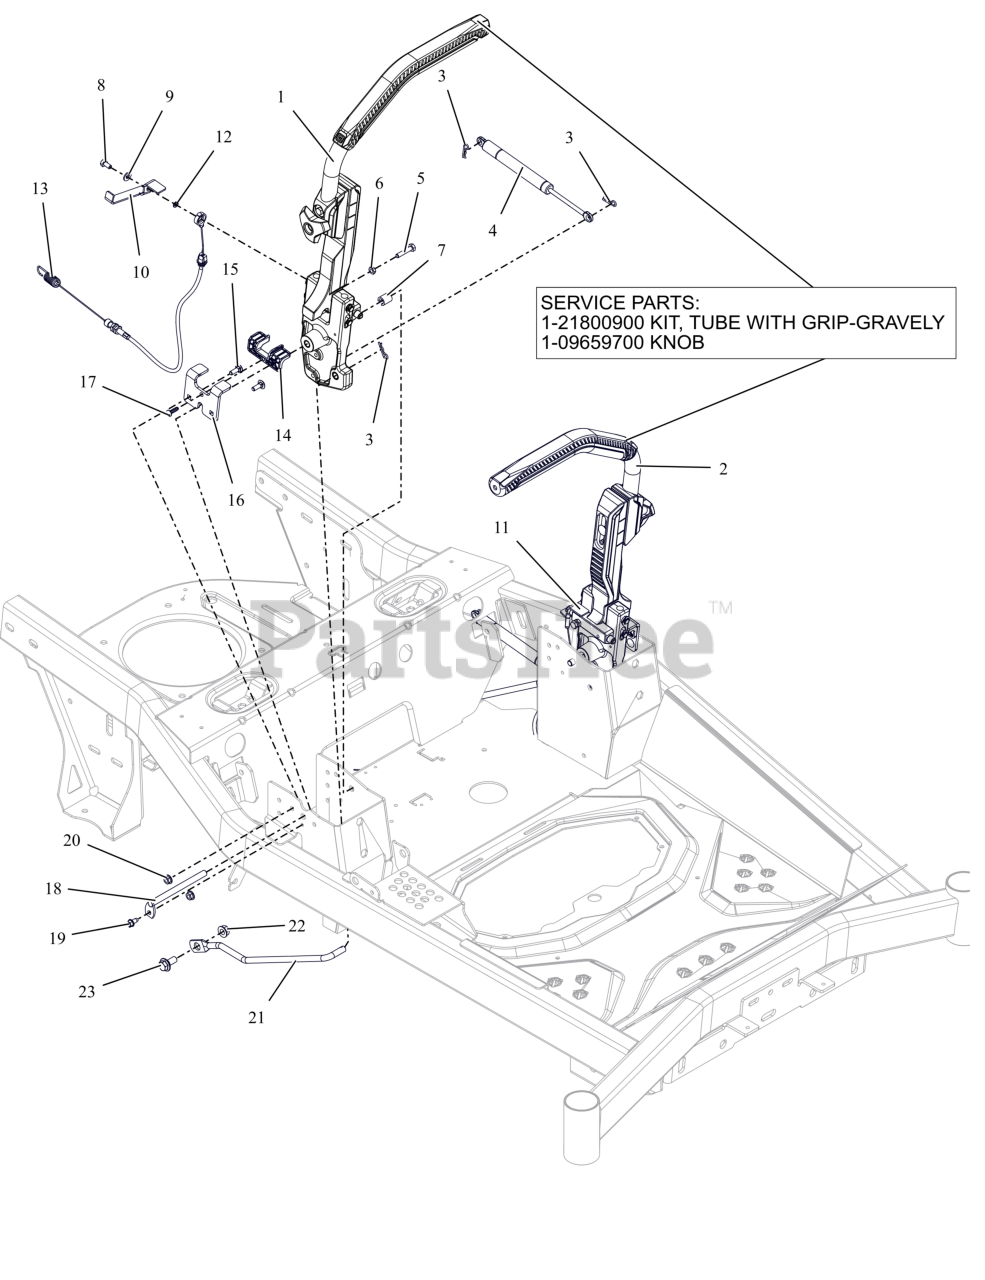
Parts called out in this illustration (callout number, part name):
1	ASM- CONTROLS -RH-GRAVELY
2	ASM- CONTROLS -LH -GRAVELY
3	PIN, HAIR #213 .08X1.19 ZCC
4	DAMPER- STRAIGHT MOUNT
5	BLT, HEX 0.25-20X1.25F GR5 ZCC
6	NUT-JAM .250-20 G2 ZCC
7	SPCR- SNAP-ON 1/2 X 1 1/2
8	BLT, HEX 0.375-16X1 GR5 EP80 ZC120
9	WSHR,FLT .281X.625X.065 ZCC
10	BRKT, PARKING BRK ENG R (BLACK)
11	BRKT- PARKING BRK ENG R-BLACK
12	WSHR-FLT .250X.406X.050 ZCC
13	CABLE- PARK BRAKE
14	STEERING, PLASTIC LINER
15	BLT, RHSN .25-20X.750 G5 ZCC
16	PLATE- BRAKE STOP
17	SCR-TAP 12-14X.75PLSTITE @BLZC
18	PIN- FIXED STEERING PIVOT
19	SCR-TAP .25-20X.50 HWH ZCC
20	NUT-LK-CTR-FLG .25-20 ZC120
21	WIREFORM- STEERING LINKAGE
22	NUT-LK-CTR-FLG .375-16 GF ZCC
23	BLT- SHLDR .375-16X.100X.72
